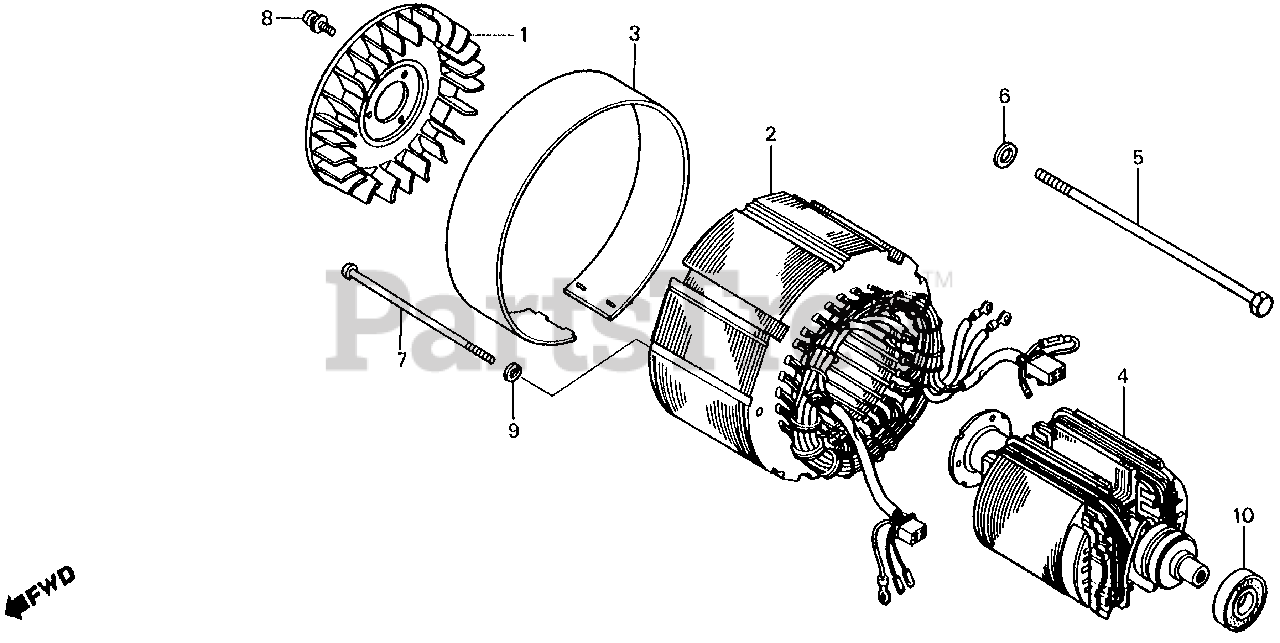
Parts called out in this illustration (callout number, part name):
1	FAN, GENERATOR COOLING
2	STATOR ASSY.
3	COVER, STATOR *R8* (BRIGHT RED)
4	ROTOR (EM)
5	BOLT, HEX. (8X190)
6	WASHER (8MM)
7	SCREW, PAN (5X130)
8	SCREW-WASHER (5X14)
9	WASHER, SPRING (5MM)
10	BEARING, RADIAL BALL (6203UU)
